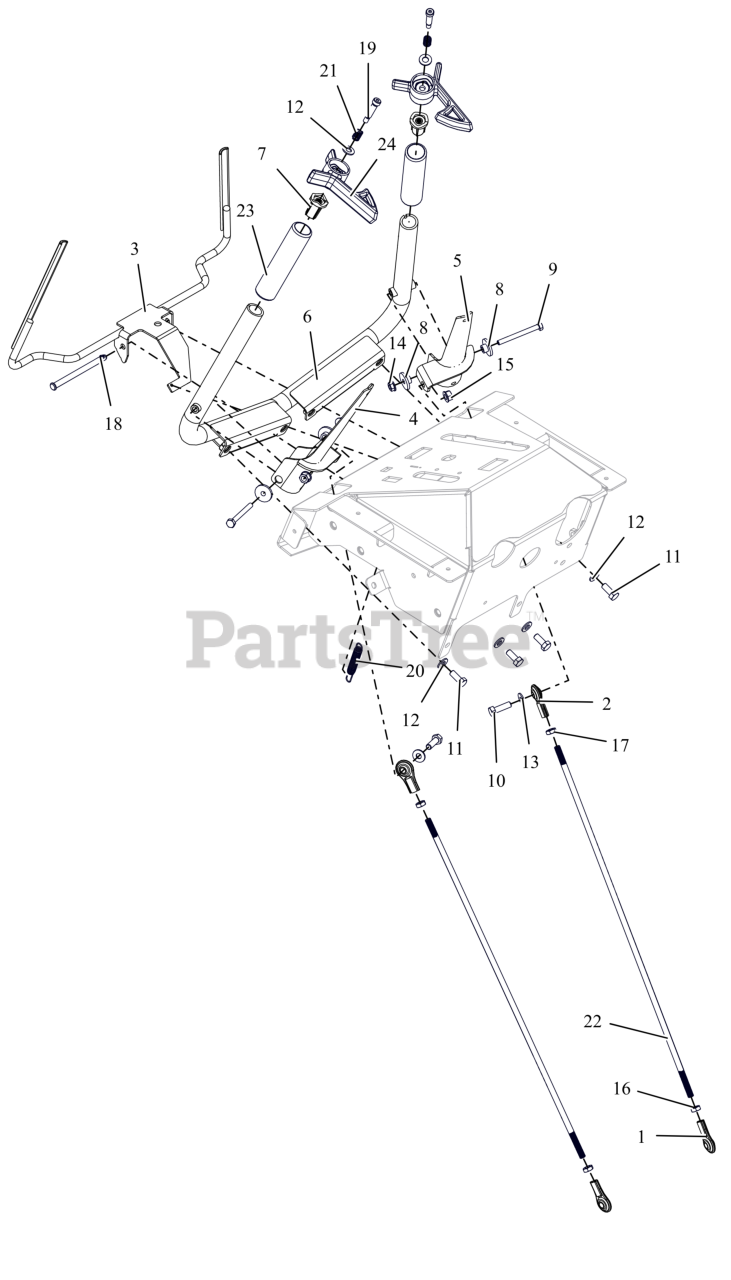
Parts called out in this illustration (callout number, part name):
1	ALIGNABALL, 5/16 RH THREAD
2	ALIGNABALL, 5/16 LH THREAD
3	WLDMT, OPERATOR PRESENCE LEVER (BLACK)
4	WLDMT, RH OPERATOR DRIVE PADDLE (BLACK)
5	WLDMT, LH OPERATOR DRIVE PADE (BLACK)
6	WLDMT, HANDLEBAR (BLACK)
7	BASE, NEUTRAL LOCK
8	BSHG-FLG .265X.448X.375X1.00
9	BLT, HEX 0.25-20X2.5 GR8 ZCC
10	BLT,HEX .31-18X1.00 G5 ZCC
11	BLT,HEX .31-18X.75 G5 ZCC
12	WSHR,FLT .344X.688X.065 ZCC
13	WSHR, FLT .312X.734X.065 ZCC
14	NUT-LK-CTR-FLG .25-20 ZC120
15	NUT,LK-CTR-FLG .31-18 GF ZCC
16	NUT-JAM .312-24 ZCC
17	NUT, JAM-LH .312-24 ZCC
18	PIN, SLIC-.3125X4.015X3.625 -ZCC
19	BLT-SHLDR .313X1.00X.25-20
20	SPRING, EXTENSION
21	SPRG, COMPRESSION
22	ROD, STEERING
23	GRIP, HANDLEBAR
24	LOCK, NEUTRAL ROTARY
